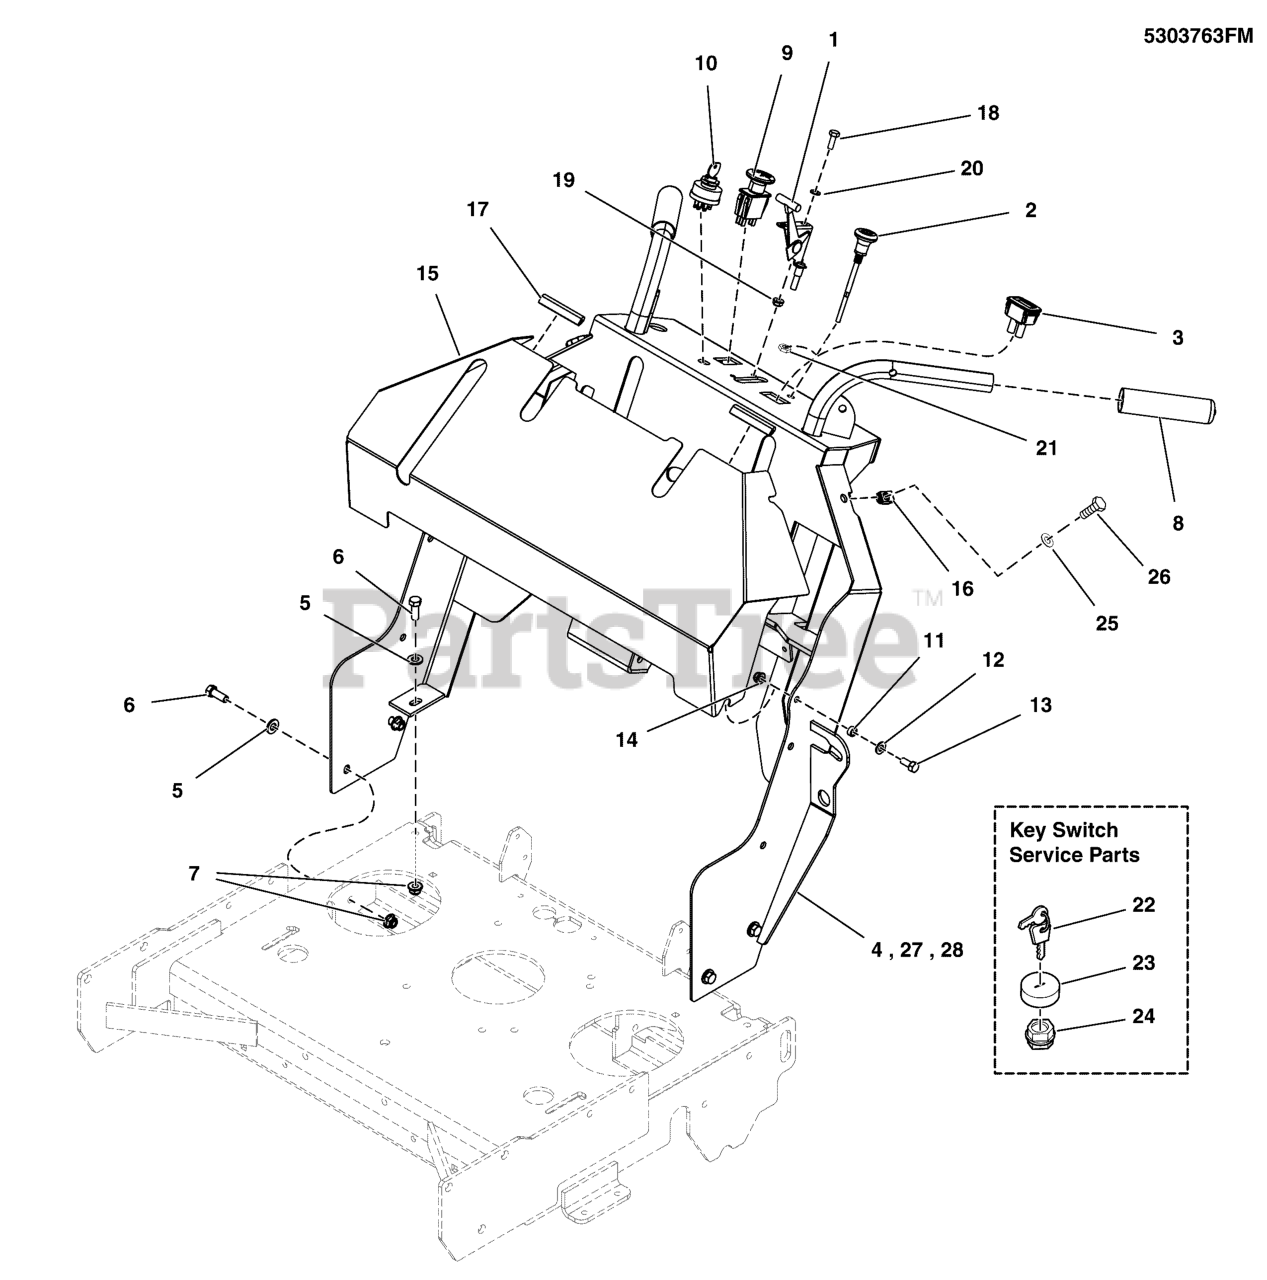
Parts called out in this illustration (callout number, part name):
1	CABLE, THROTTLE, 43" DETENTED
2	CABLE, CHOKE CONTROL, 51 (Z)
3	* HOUR METER, ASSEMBLE
4	** WELD, HANDLE BARS, F/SW35 - RED
5	WASHER, 3/8 GD.9 FLAT
6	BOLT, 3/8-16 X 1" GD5 CZ
7	NUT, 3/8-16 HEX NYLOCK FLANGE
8	GRIP, FOAM, .940" X 4.62" X .187"
9	PTO SWITCH, MOMENTARY, SMALL KNOB
10	SWITCH, IGNITION, 6 POST
11	SPACER, .33 X .50 X .25, CZ
12	WASHER, 5/16" SAE
13	BOLT, 5/16-18 X 1 GD5
14	NUT, 5/16-18 HEX NYLOCK FLANGE
15	ASSM, HB GUARD W/DECALS, FW35 - CE
16	BODY CLIP, 5/16-18-7GA MATERIAL
17	BLACK BODY MOLDING, 3" LONG
18	BOLT, 1/4-20 X 3/4 GD5 YZ
19	NUT, 1/4-20 HEX NYLOCK FLANGE
20	WASHER, 1/4 SAE
21	NUT, 3/8-24 HEX JAM
22	KEY, IGNITION MOLDED SET
23	COVER, PLASTIC, SNAP ON
24	PLASTIC NUT
25	WASHER, 5/16" SAE
26	BOLT, 5/16-18 X 1 GD5 CZ
27	** WELD, HANDLE BARS, F/SW35 - RED
28	** WELD, HANDLEBARS, W35, STD - RED
